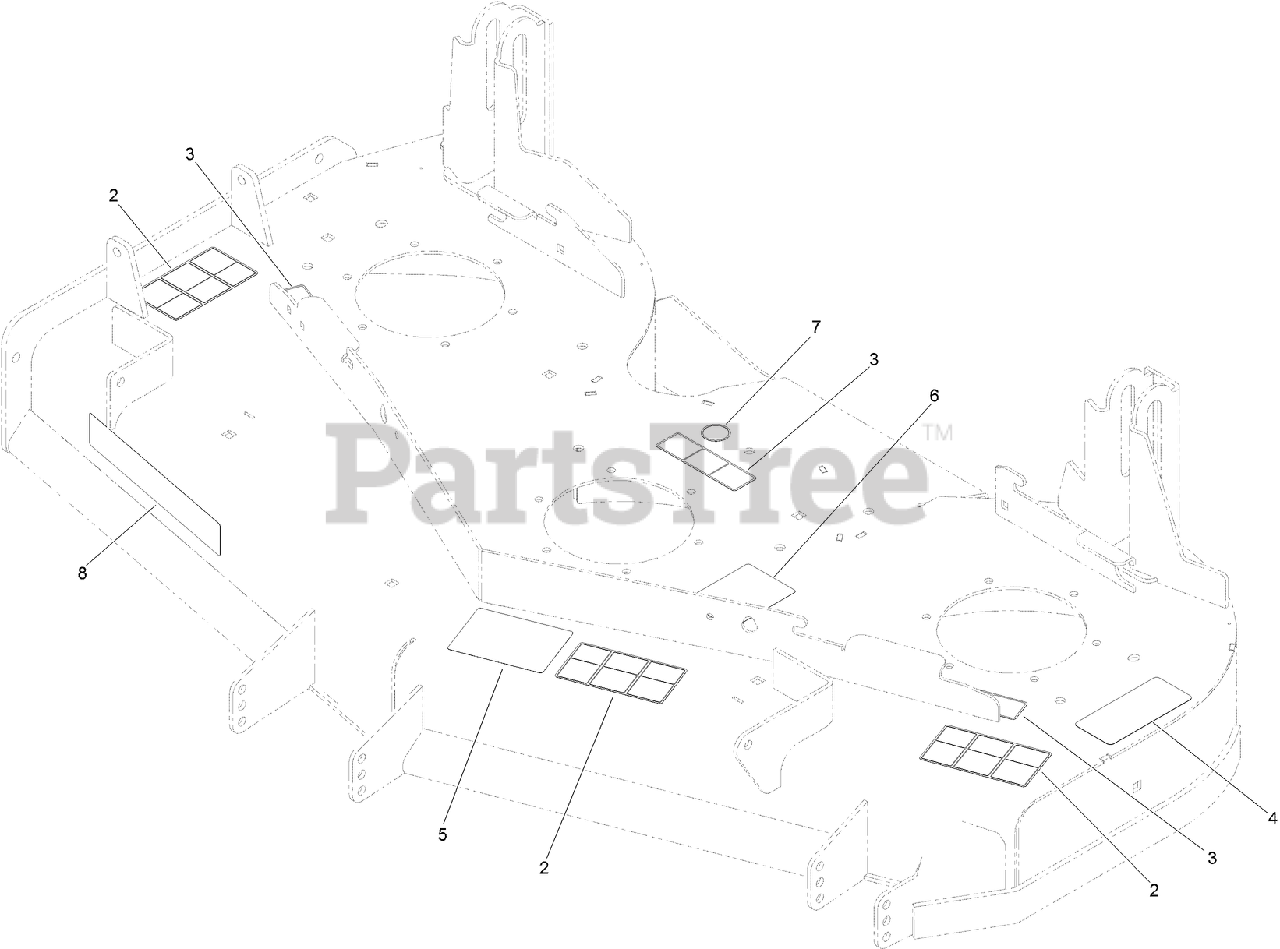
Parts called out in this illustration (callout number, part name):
2	DECAL-DANGER
3	DECAL-MISSING, COVER
4	DECAL-TORQUE, BLADE BOLT
5	DECAL-SCALP, ANTI
6	DECAL-ROUTING, DECK BELT
7	DECAL-GREASE
